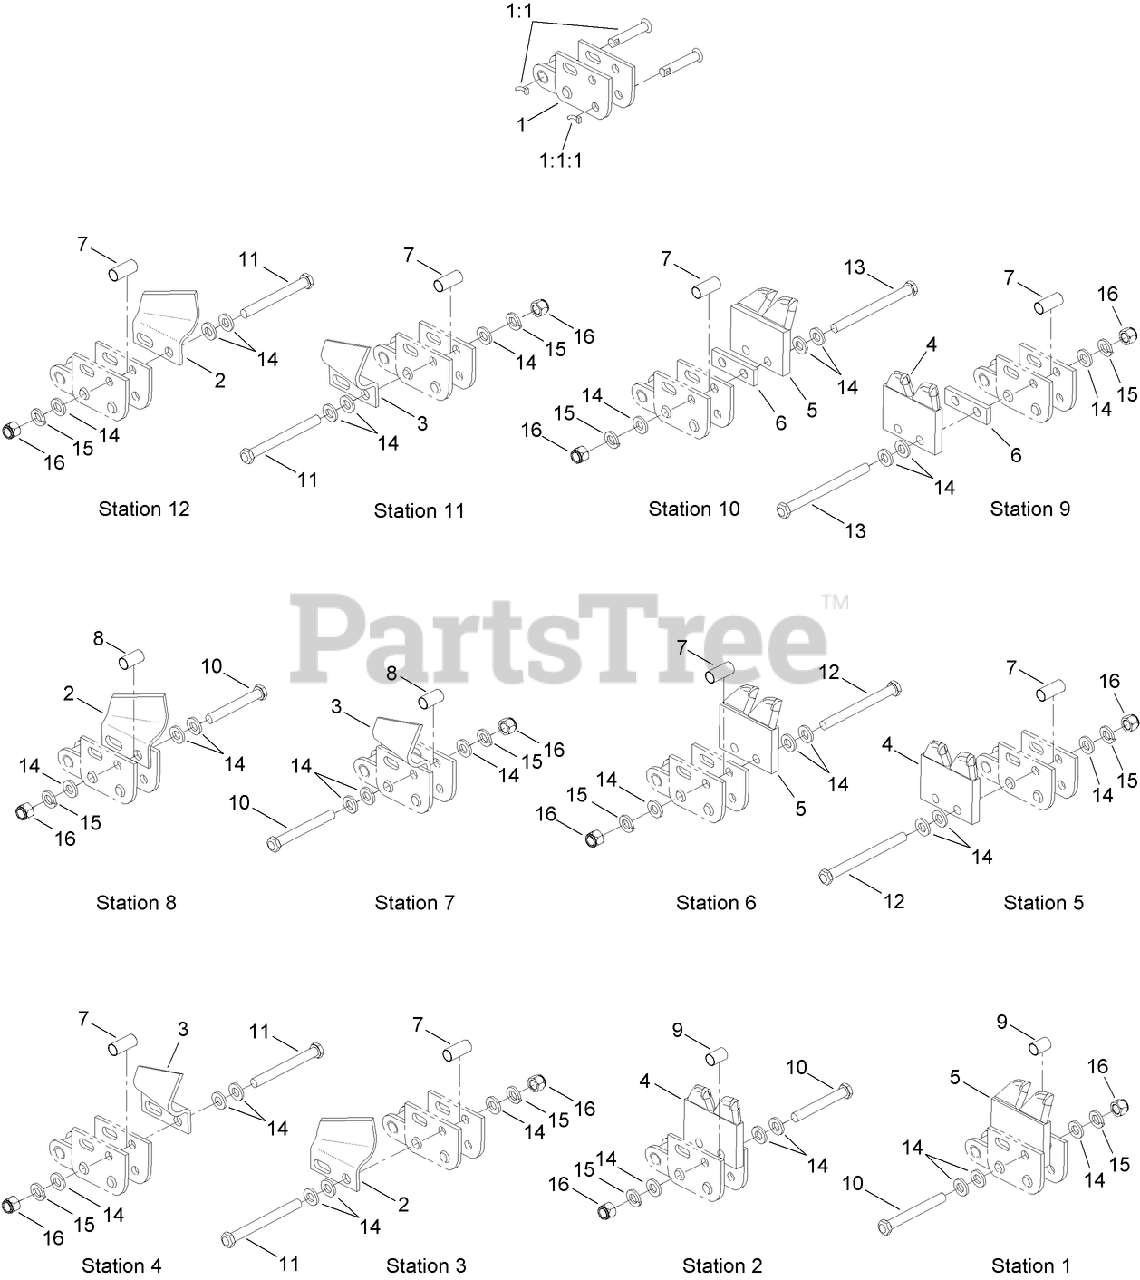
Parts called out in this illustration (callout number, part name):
1	CHAIN REPAIR LINK ASM
1:1	NOTCHED PIN AND KEEPER ASM
1:1:1	PIN-KEEPER
2	CUTTER-CUP, MIXED, LH
3	CUTTER-CUP, MIXED, RH
4	TOOTH-TERMINATOR, RH
5	TOOTH-TERMINATOR, LH
6	SPACER-FLAT
7	SPACER-TUBE, OUTSIDE MOUNT
8	SPACER-TUBE, INSIDE CUP MOUNT
9	SPACER-TUBE, INSIDE ADAPTER
10	BOLT-HH
11	BOLT-HH
12	BOLT-HH
13	BOLT-HH
14	WASHER-FLAT
15	WASHER-LOCK
16	NUT-LOCK
